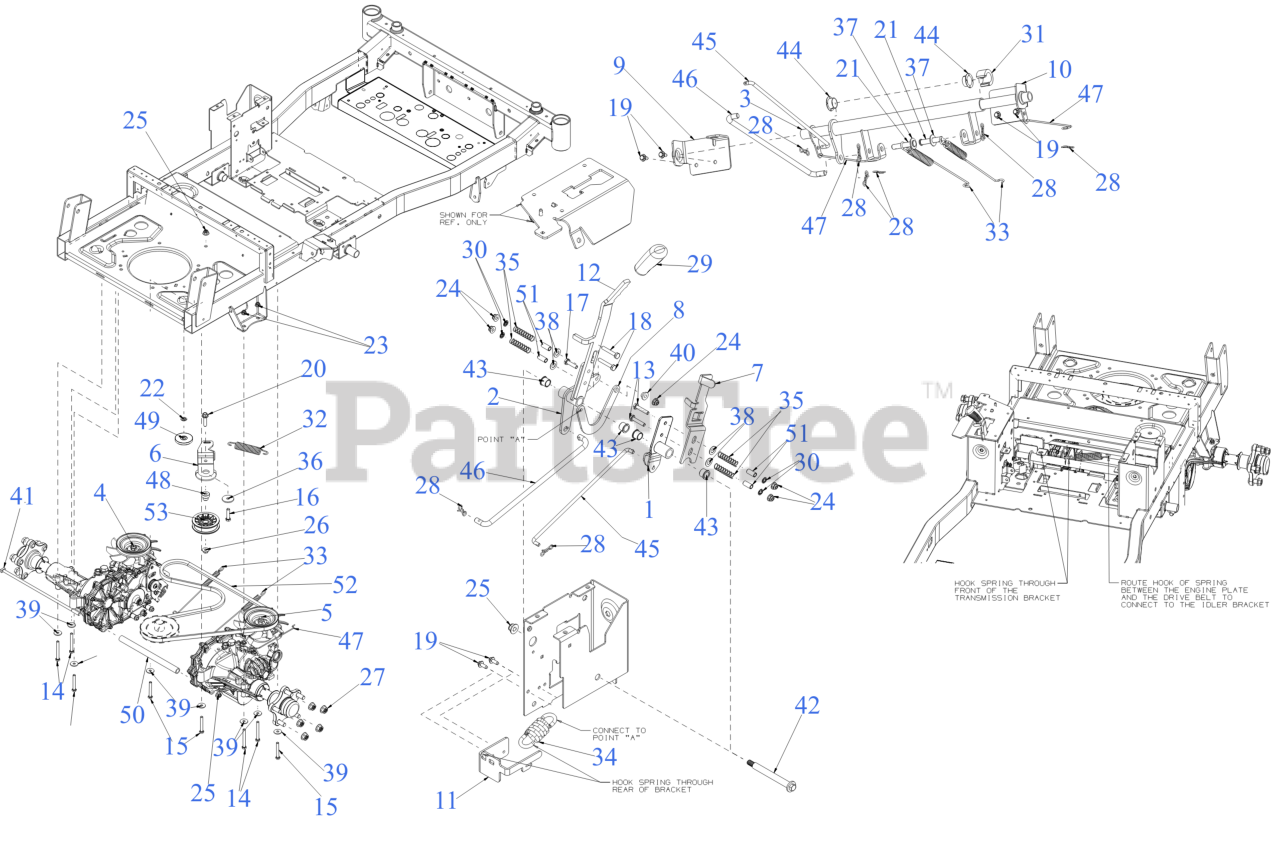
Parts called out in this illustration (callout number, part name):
1	BYPASS LEVER PIVOT ARM
2	PARK BRAKE PIVOT ARM
3	BRAKE PIVOT SHAFT
4	HYDRO TRANSMISSION (LH)
5	HYDRO TRANSMISSION (RH)
6	HYDRO DRIVE IDLER BRACKET
7	TRANSMISSION BYPASS LEVER
8	OVER CENTER LINK
9	BRAKE SHAFT SUPPORT (RH)
10	BRAKE SHAFT SUPPORT (LH)
11	SPRING MOUNTING BRACKET
12	PARK BRAKE LEVER
13	HEX SCREW 1/4-20 x 1.25
14	HEX SCREW 5/16-18 x 2.75
15	HEX SCREW 5/16-18 x 2.25 GR5
16	SCREW 3/8-16 x 1.50
17	SCREW 1/4-20 X1.00 GR5
18	SCREW 1/4-20 x 1.50 GR.5
19	SCREW M6-1 x .625
20	HEX HEAD BOLT (3/8-16:1.50 GR8)
21	CLEVIS PIN 3/8 x 1.87
23	FLANGE LOCK NUT 5/16-18
24	FLANGE LOCK NUT
26	FLANGE LOCK NUT
27	HEX FLANGE NUT 1/2-20 GR8
28	BOW TIE COTTER PIN 1/4-5/16
30	RETAINER-BOLT .25ID x .50OD
31	SPACER: .76ID x .75
32	EXTENSION SPRING .925 x 5.37
33	EXTENSION SPRING .60 DIAx9.09
34	EXTENSION SPRING 1.09x3.25
35	COMPRESSION SPRING
36	FLAT WASHER .390x1.500x.134
37	FLAT WASHER
38	WASHER THRUST .375X.70X.030
39	FLAT WASHER 1.0 OD:.331 ID
40	SHOULDER SPACER
41	SUPPORT TUBE ROD
42	SHOULDER SCREW .491x3.937 3/8-16
43	FLANGE BUSHING
44	FLANGE BEARING .75 x 1.125 x .375
45	BYPASS LINK
46	BRAKE LINK
47	HYDRO BYPASS ROD .100 DIA
48	SHOULDER SPACER
49	SHOULDER SPACER
50	SUPPORT TUBE
51	SPACER .252x.350x.760
52	TRANSMISSION DRIVE BELT A x 67
53	FLAT IDLER PULLEY 3.00 OD
